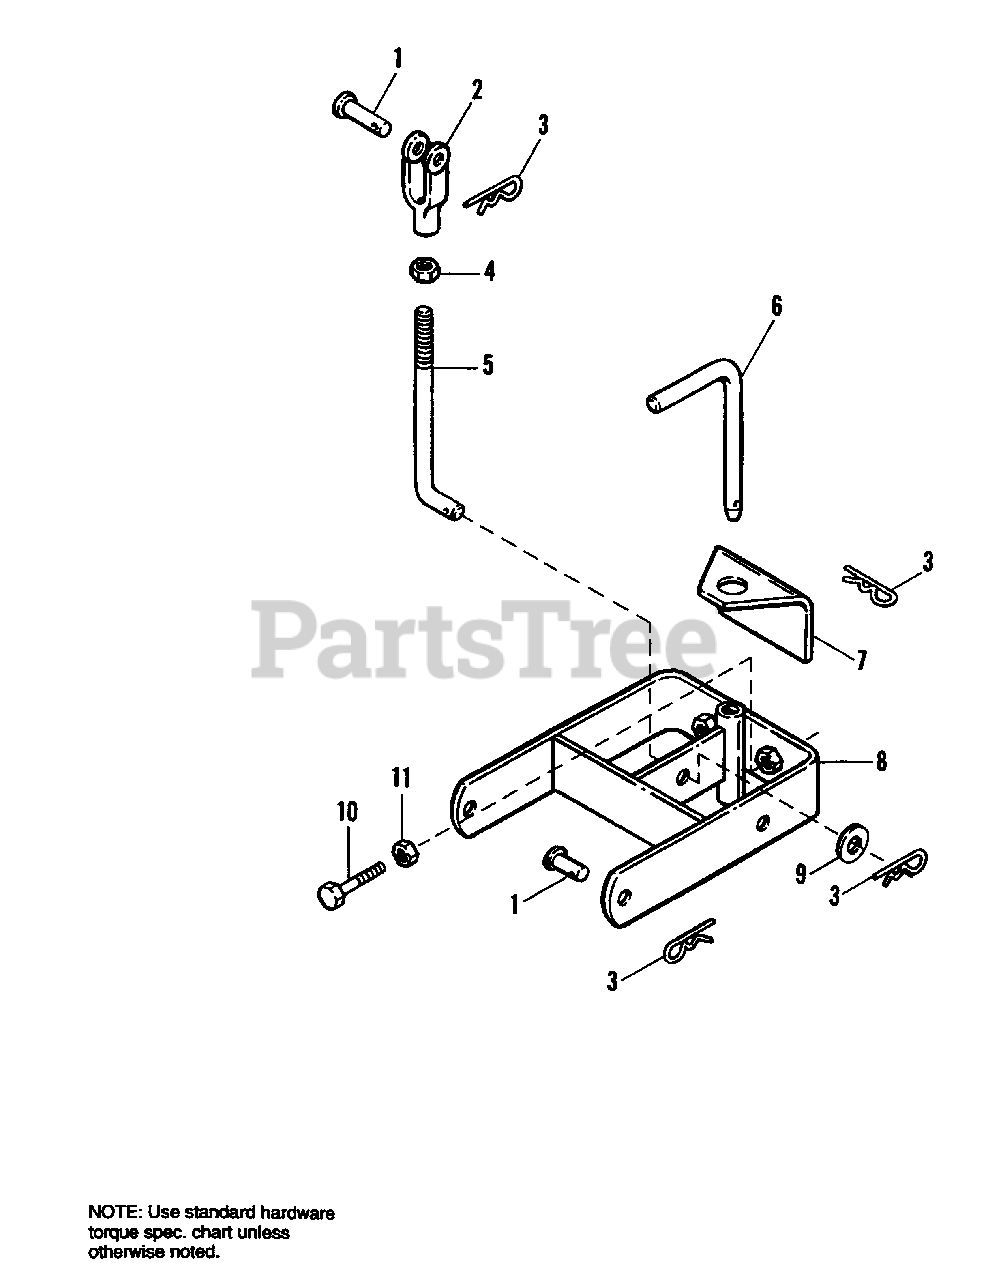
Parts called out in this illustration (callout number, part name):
1	PIN, Yoke
2	YOKE, End Adj.
3	CLIP, Spring
4	NUT, Hex, Jam, 1/2-20
7	PLATE, Stabilizer
8	CLEVIS ASSY.
9	WASHER, 17/32 x 1-1/4 x 1/16
10	CAPSCREW, Hex Hd., 5/8-11 x 2-1/4
11	NUT, Hex, 5/8-11
